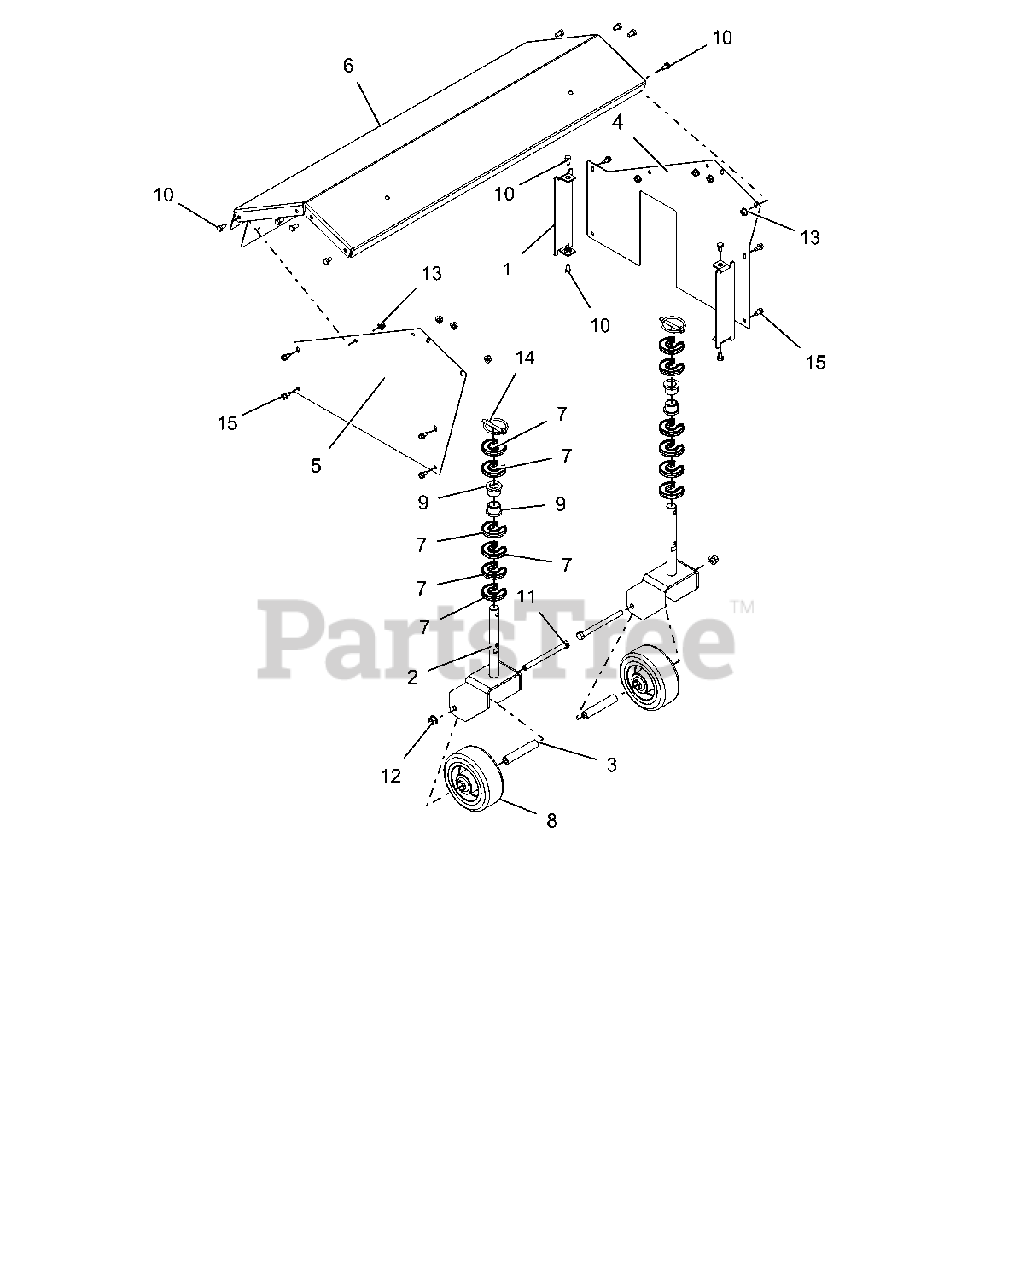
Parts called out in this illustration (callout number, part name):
1	COVER, END (BLACK)
2	FRAME, CASTER (BLACK)
3	SPCR, CASTER WHEEL
4	COVER, LH SIDE-BRUSH (ORANGE)
5	COVER, RIGHT HAND SIDE (ORANGE)
6	COVER, TOP - 28" BRUSH
7	CLIP, HOC FIXED
8	WHEEL, CASTER - 5" OD
9	BUSHING, FLANGE
10	BLT-HEX .25-20X.50 GR5 YWZC
11	BLT-HEX .38-16X4.50 GR5 YWZC
12	NUT, LK-TOP-FLG .38-16 YWZC
13	NUT, LK-TOP-FLG .25-20 YWZC
14	PIN, LYNCH - .25 X 1.25
15	SCR-TAP .25-20X.50 HWH TR YWZ
